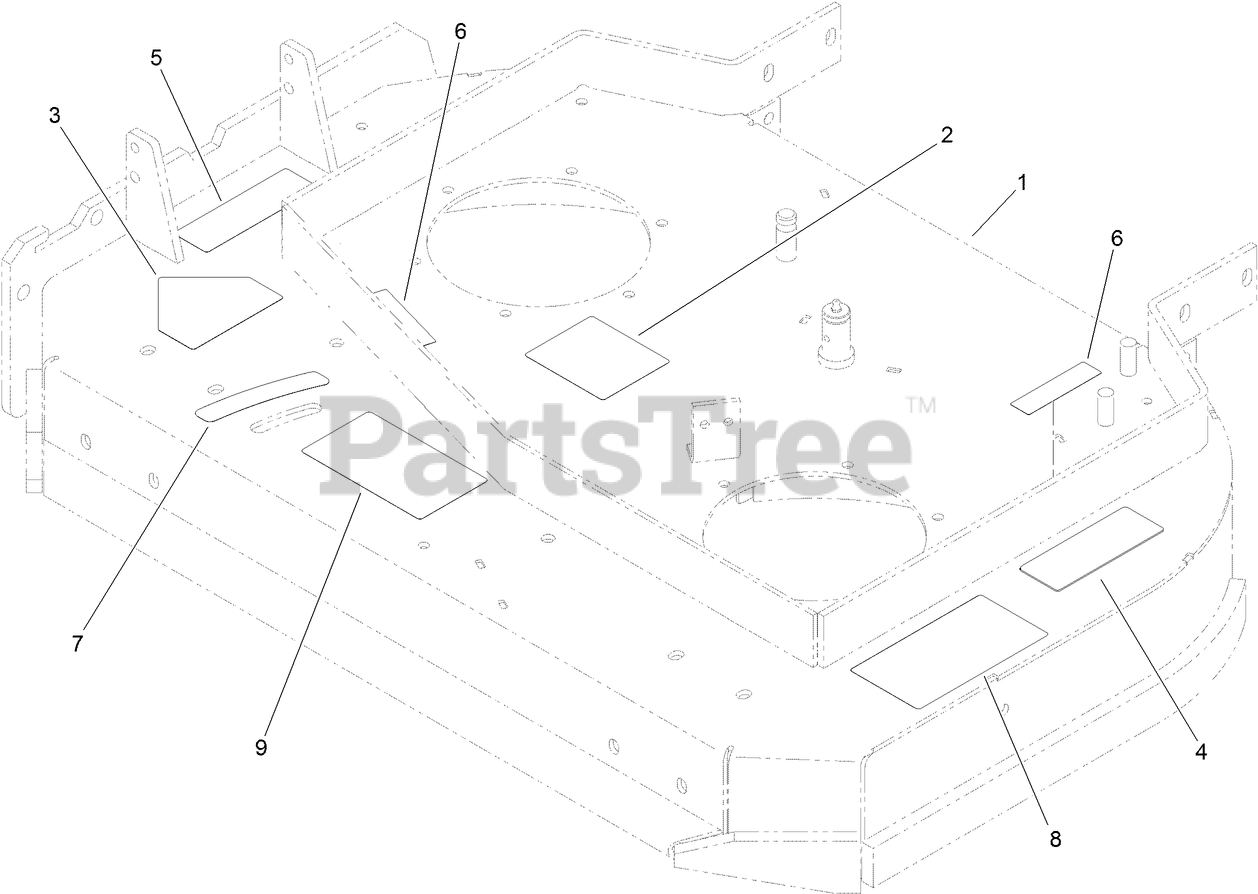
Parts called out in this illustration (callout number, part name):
1	36 INCH DECK ASM
2	DECAL-ROUTING, BELT
3	DECAL-DANGER
4	DECAL-TORQUE, BOLT
5	DECAL-WARNING
6	DECAL-COVER, MISSING
7	DECAL-SETTING, BAFFLE
8	DECAL-DANGER, THROWN OBJECT
9	DECAL-ADJUSTMENT, BAFFLE
